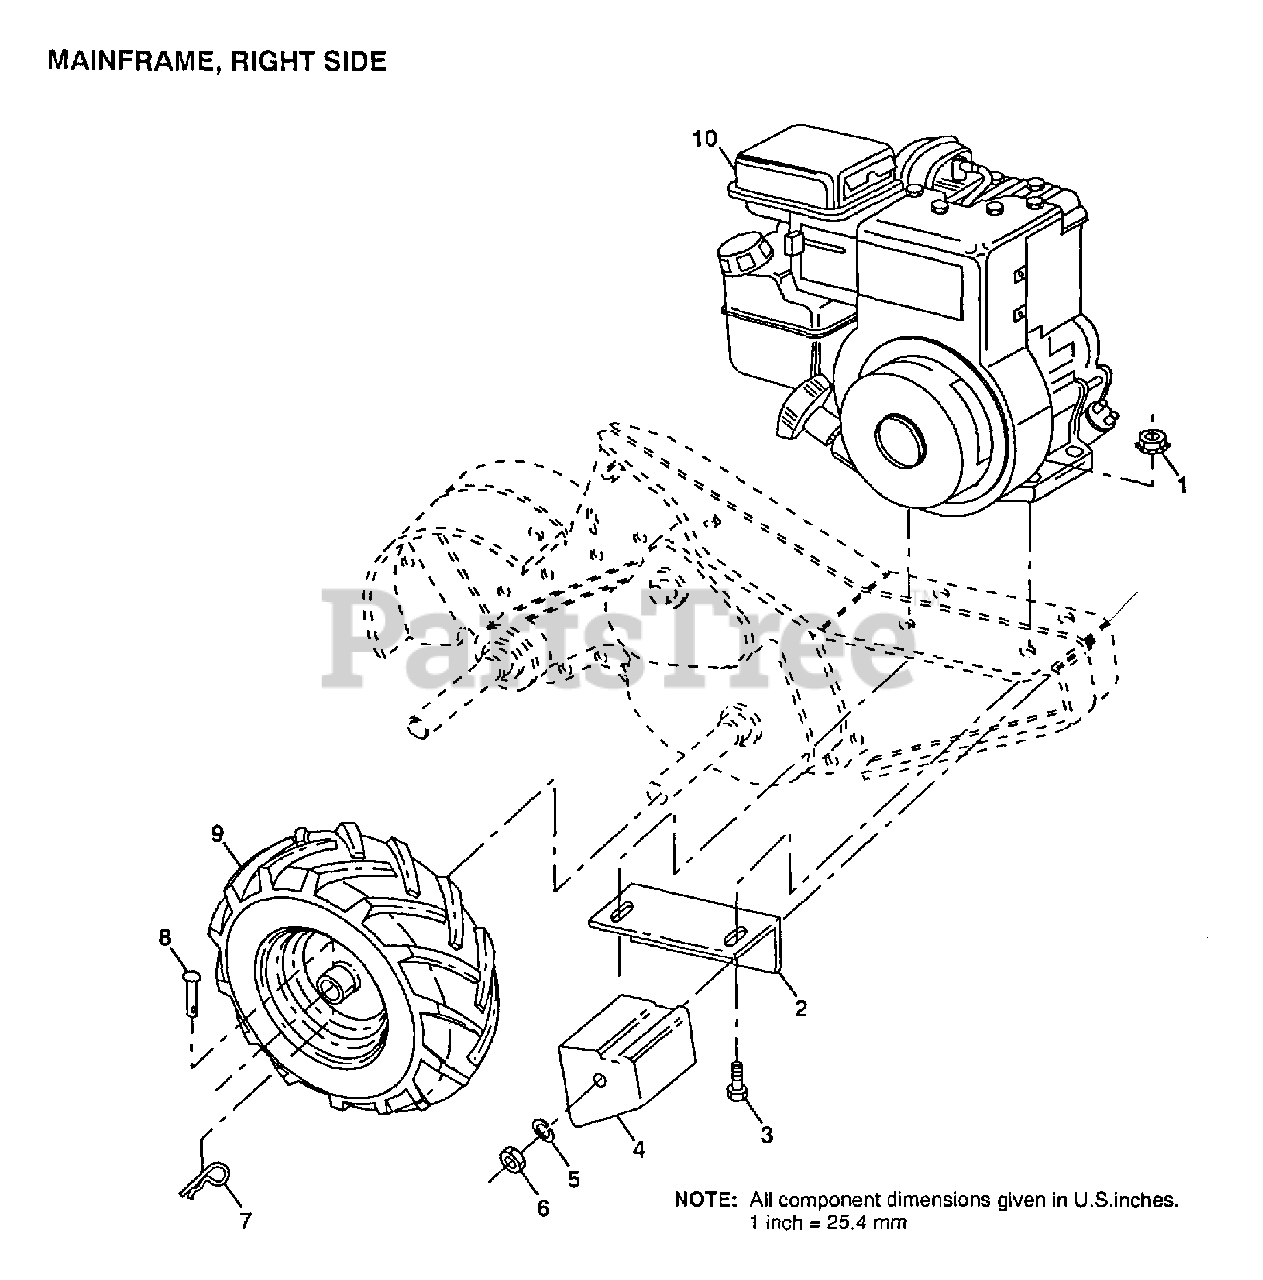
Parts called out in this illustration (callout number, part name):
2	BRACKET RH CRT
3	BOLT.HEX.5/16-1.5
4	COUNTERWEIGHT CRT
5	LOCKWASHER
6	NUT.HEX.3/8-16UNC
7	RETAINER M
8	RIVET.DRILL.1.75
9	TIRE.CHV.13X5.0-6
